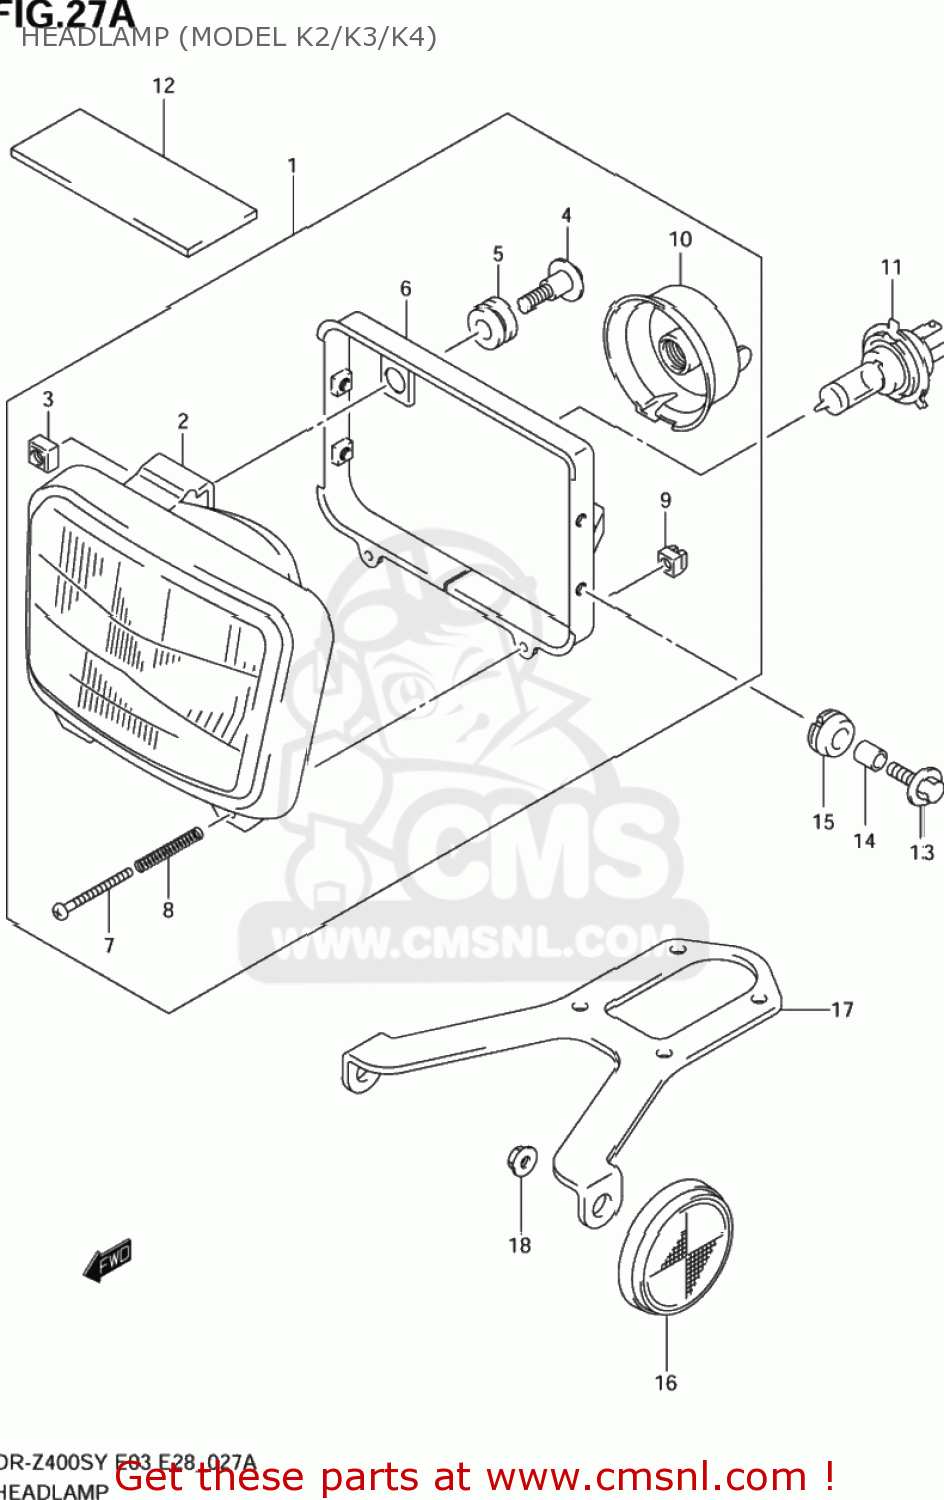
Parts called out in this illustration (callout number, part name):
1	HEADLAMP ASSY
2	UNIT ASSY
3	NUT
4	SCREW,MOUNTING
5	CUSHION
6	HOUSING
7	SCREW,ADJUSTING
8	SPRING,ADJUSTING
9	NUT,ADJUSTING
10	COVER,SOCKET
11	BULB(12V60/55W,H4)
12	PROTECTOR,WIRING HARNESS
13	BOLT(6X20)
14	SPACER(6.5X10X10)
15	CUSHION
16	REFLECTOR,REFLEX FR
17	BRACKET,FR SIDE RR
18	NUT
